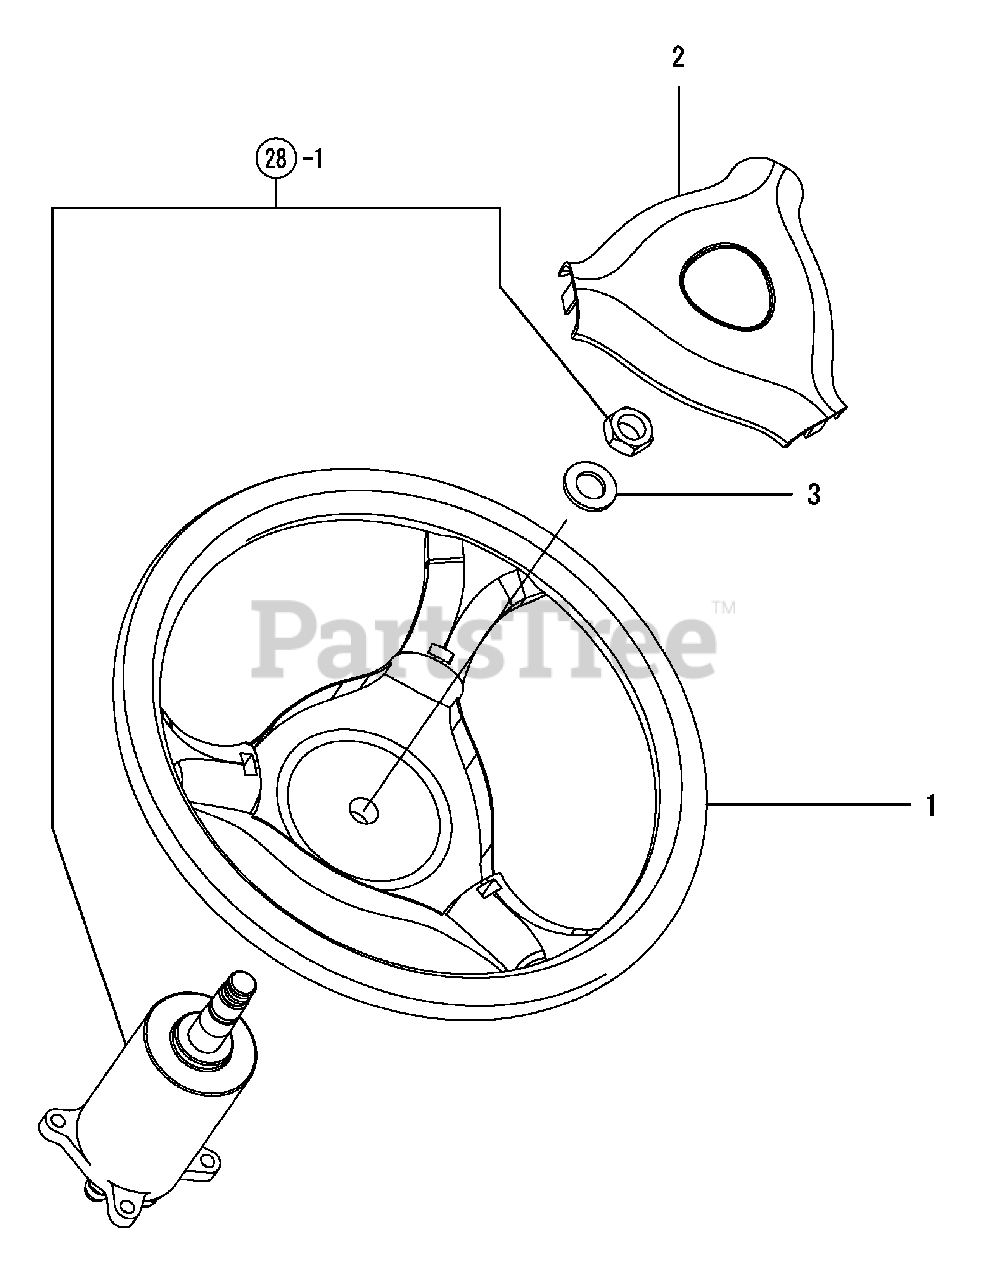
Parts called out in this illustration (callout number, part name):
1	WHEEL, STEERING
2	CAP,STEERING WHEEL
3	WASHER 16, POLISHED
